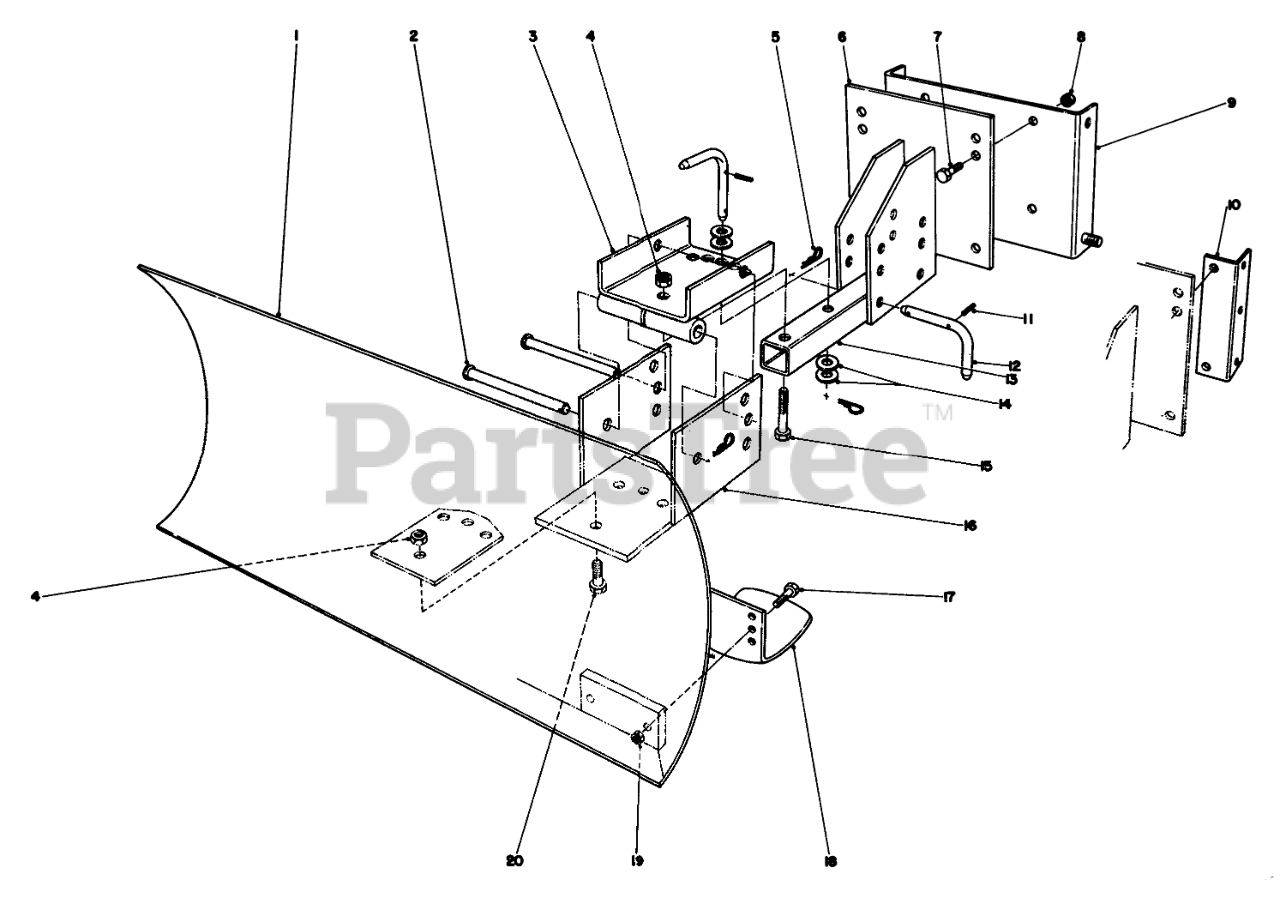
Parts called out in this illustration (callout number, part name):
1	Blade
2	PIN-CLEVIS
3	Swivel Bracket
4	1/2-13 CONELOCK NUT
5	PIN-HAIR
6	Mounting Plate
7	SCREW-HH
8	NUT-LOCK, CONE
9	Mounting Plate (Used with 826 & 1132 Units only)
10	Mounting Rail (used with 421 units only)
11	PIN-SPRING
12	Pivot Pin (Incl. Ref. #11)
13	Blade Tongue
14	WASHER-FLAT
15	SCREW-HH
16	Blade Adjustment
17	SCREW-HH
19	NUT-LOCK, CONE
20	SCREW-HH
